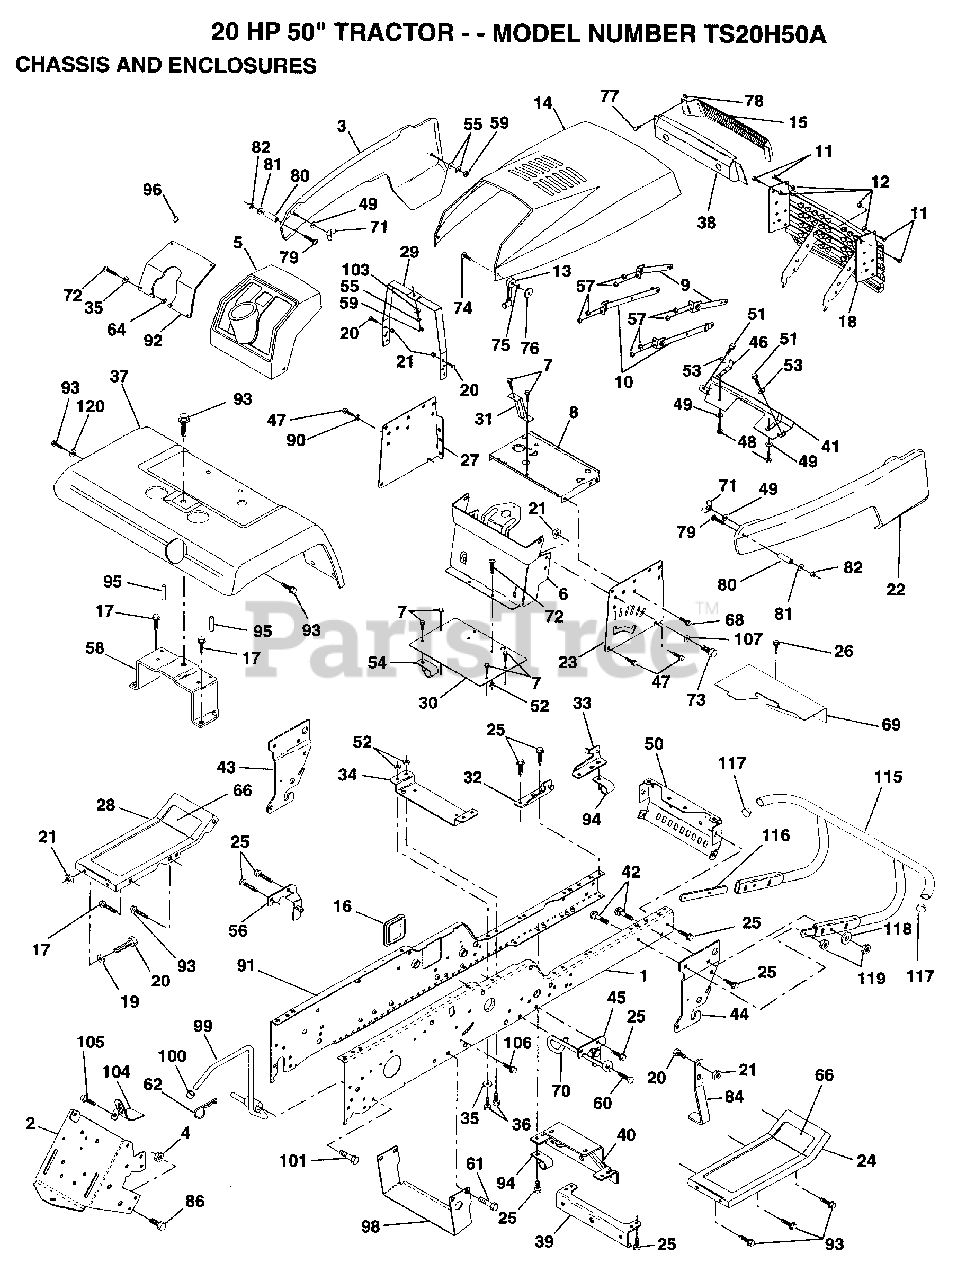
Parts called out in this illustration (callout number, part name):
2	DRAWBAR GT
4	NUT.7/16
5	DASHBOARD BLACK
6	DASH ASM LOWER
7	SCREW
8	SUPPORT BATRY VGT
12	NUT
13	HOOD LATCH T
15	LENS LT
16	COVER ACCESS
17	SCREW
18	GRILLE.ASM.PNT.YP
19	WASHER
20	BOLT
21	NUT
22	PANEL SIDE RH
25	SCREW
26	SCREW
29	SUPPORT ASS'Y
30	SADDLE SLKSCRNED
31	BRACE.SUPT.STRG
32	BRACKET ASM FRAME
33	BRACKET ASM FRAME
34	BRACKET.ENG.SUPT.
35	WASHER
36	BOLT
37	FENDER.PNT.
39	BRACKET.AXLE.FRT.
42	BOLT.3/8-14X1.25
43	BRACKET.SUS.FT.LH
44	BRACKET.SUS.FT.RH
47	SCREW LT
48	SCREW
49	WASHER
50	BRACKET.CHASSIS.
51	SCREW HEX CRT
52	NUT
53	WASHER
54	"CLIP,INSULATOR"
55	WASHER PM
57	NUT
58	BRKT.ASM.FENDER
60	SCREW
61	SCREW
62	RETAINER M
66	FOOTREST PAD
68	SCREW LT
69	SHIELD.HEAT.MUF
70	GUIDE.BELT.MID.SP
72	SCREW
73	BOLT
74	SCREW
75	LOCKWASHER
76	WELDNUT
78	"""J"" FASTENER LT"
79	SCREW
80	SPACER LT
81	WASHER
84	STOP.OVER.CENTER
86	BOLT
90	LOCKWASHER
92	PLATE YP SLKSCR
93	SCREW LT
94	CLIP GTV
95	NUT-PUSH YT
96	PLUG-DASH T
98	BRACKET SKID CHAS
99	ROD BYPASS
101	SCREW LT
103	LOCKWASHER
104	LOCK BYPASS BRKT
105	SCREW LT
106	BOLT.5/16-18X1.25
107	WASHER
115	BUMPER.ASM.W/PY
116	BRACKET.EXT.BUMP.
117	PLUG.PLASTIC
118	WASHER
120	WASHER HYT
